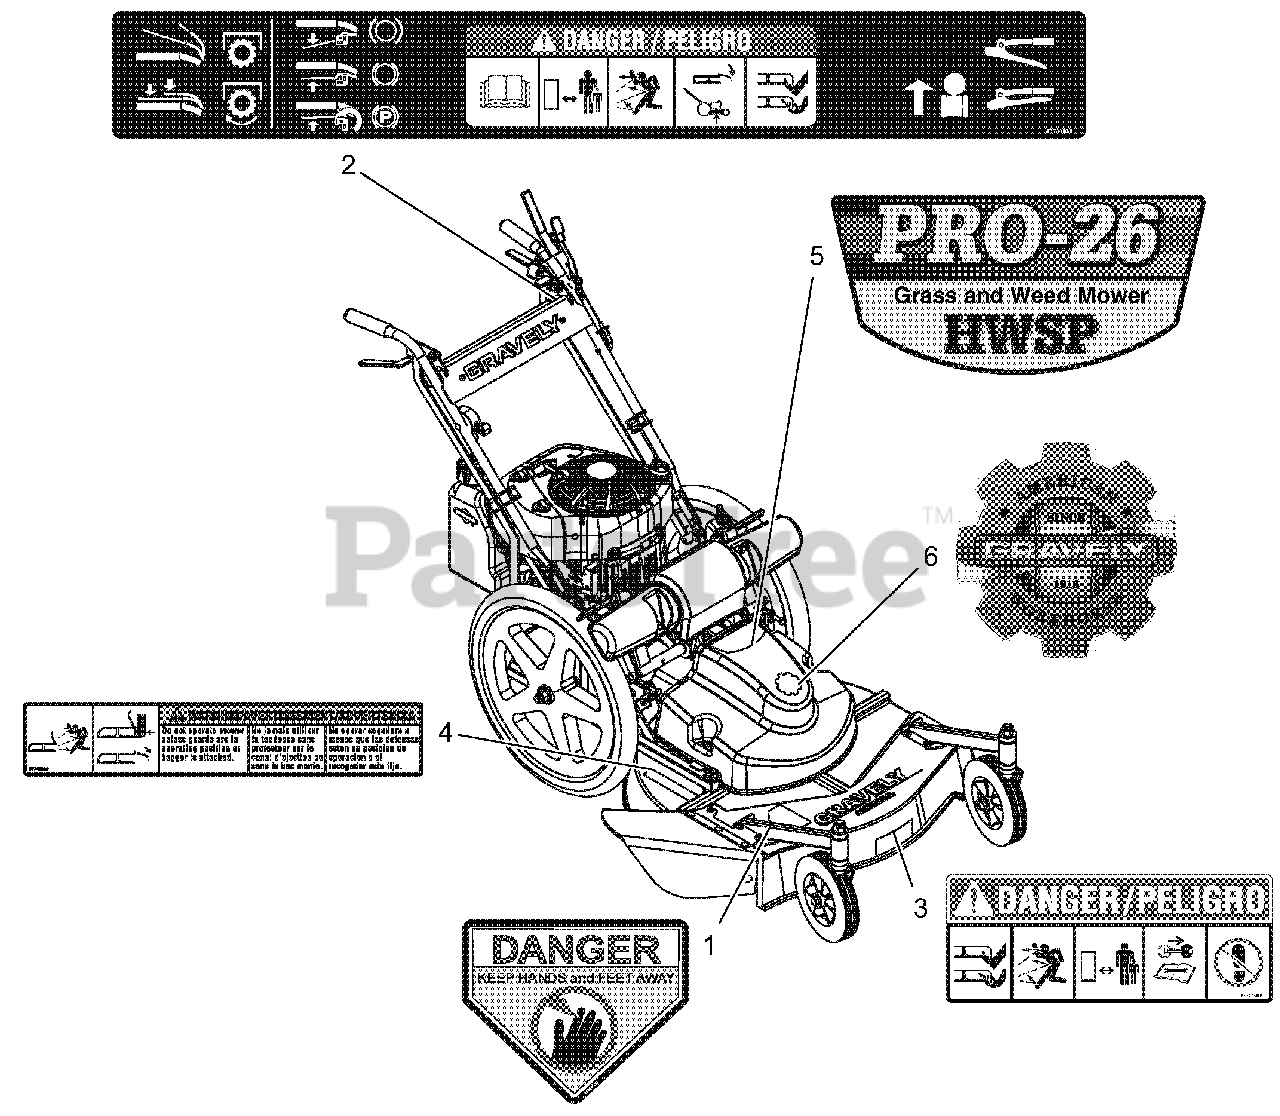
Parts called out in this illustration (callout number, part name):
1	DECAL, DANGER
2	DECAL-OPER./DANGER 26HWM
3	DECAL, MOWER PAN DANGER
4	DECAL, WARNING
5	DECAL, PRO -26 HWSP
6	DECAL, GRAVELY HERITAGE-SMALL
